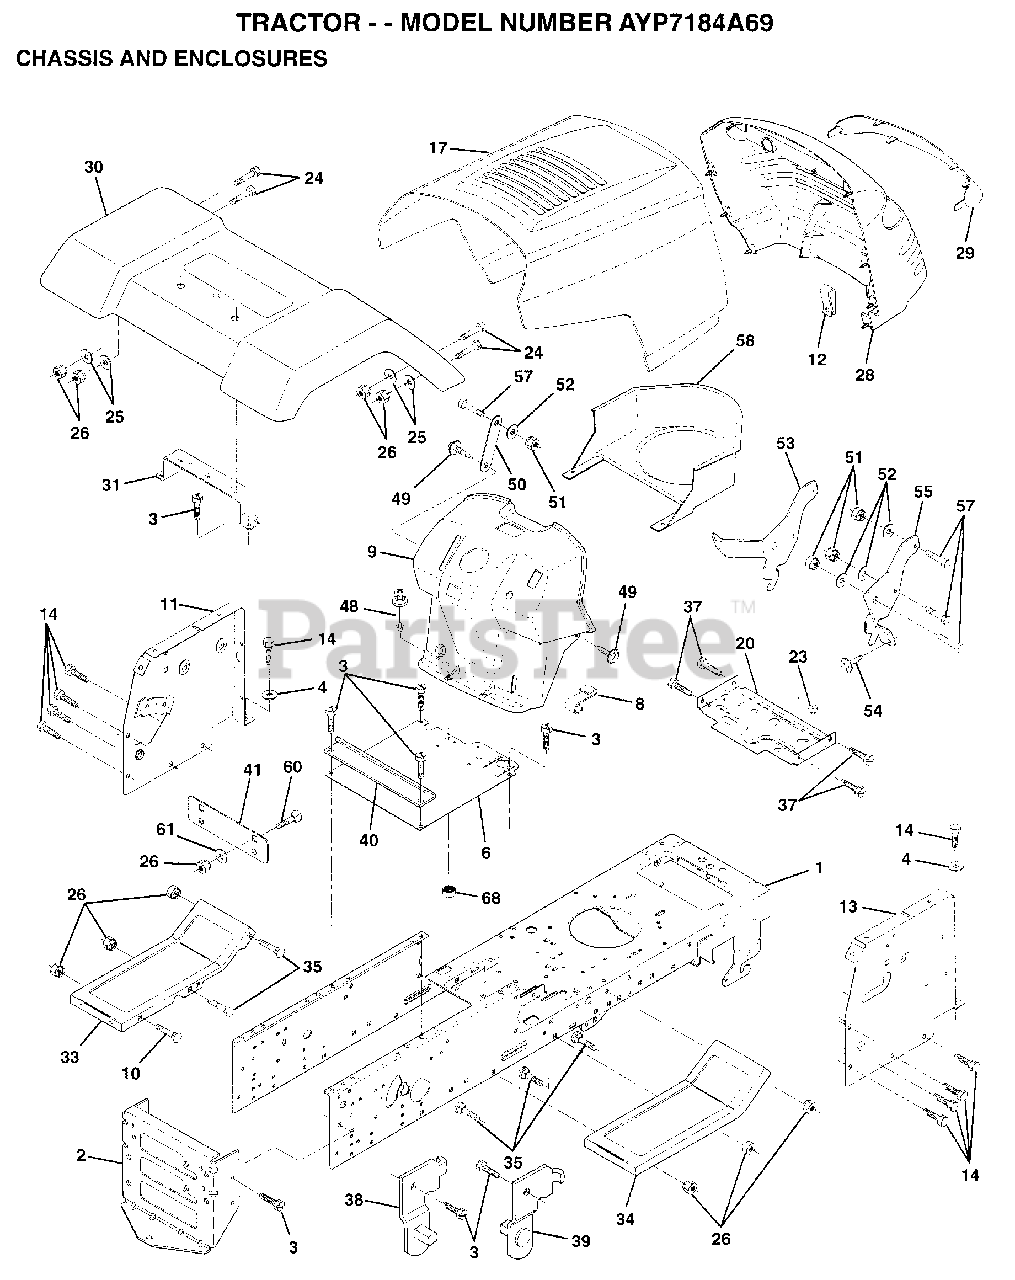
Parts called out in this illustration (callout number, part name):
1	CHASSIS.WLD.11GA
3	SCREW
4	WASHER
8	"CLIP,INSULATOR"
11	PANEL.DASH.LH.
12	CLIP.TINNERMAN
13	PANEL.DASH.RH
14	SCREW LT
20	PLATE.MTG.BTRY.TK
24	BOLT
25	WASHER
26	NUT
29	LENS GRILLE
30	FENDER
31	BRACKET SUPT FEND
33	FOOTREST LH
34	FOOTREST RH
35	BOLT
37	SCREW LT
38	BRACKET ASM LH
39	BRACKET ASM RH
40	SPACER FENDER LT
41	PLATE EXTEN FEND
48	RIVET.PUSH.PLATE
49	SCREW HEX CRT
50	BRACE SUPT DASH
51	NUT
52	WASHER
53	BRACKET.GRILLE.LH
55	BRACKET.GRILLE.RH
58	DUCT.AIR.B&S.18HP
60	BOLT
61	WASHER
68	NUT
